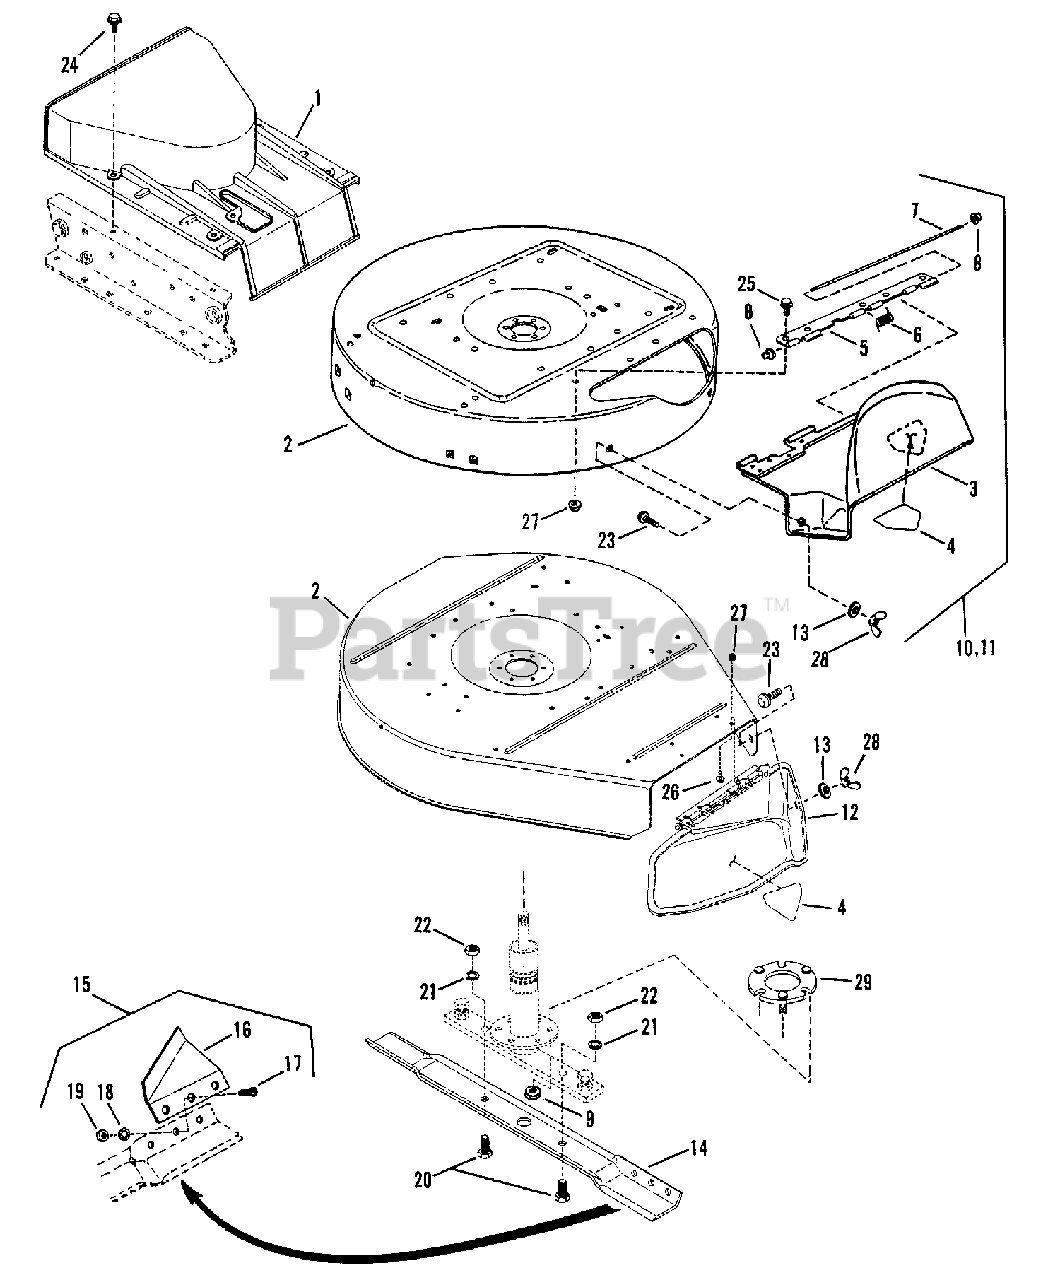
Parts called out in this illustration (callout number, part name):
1	COVER, Spindle
2	25" DECK (Includes decals)
2	26" DECK (Includes decals)
2	28" DECK (Includes decals)
2	30" DECK (Includes decals & deflector)
3	DEFLECTOR, Discharge (25" Deck)
3	DEFLECTOR, Discharge (28" Deck)
4	DECAL, Danger (Cut Finger)
5	HINGE, Deflector
6	SPRING, Hinge
7	PIN, Hinge
8	NUT, 1/4 Push
9	NUT, 3/8-16 Hex Flange Lock
10	ASSEMBLY, Discharge (25" Deck)
11	ASSEMBLY, Discharge (28" Deck)
12	DEFLECTOR, Discharge (26" & 30" Decks)
13	WASHER, 5/16 Flat
14	25" BLADE
14	26" BLADE
14	28" BLADE
14	30" BLADE
15	AIR LIFT KIT, Hi-Vac
16	AIR LIFT, Hi-Vac (3 hole)
17	SCREW, 5/16-24 x 11/16" Machine
18	WASHER, 5/16-24 Internal Tooth Lock
19	NUT, 5/16-24 Hex
20	SCREW, 1/2-20 x 1" Hex Head Cap
21	WASHER, 1/2 Internal Tooth Lock
22	NUT, 1/2-20 Hex Jam
23	BOLT, 5/16-18 x 3/4" Short Neck Carriage
24	SCREW, 1/4-20 x 5/8" Self-Tapping
25	SCREW, 5/16-18 x 5/8" Self-Tapping
26	BOLT, 5/16-18 x 1/2" Hex Flange Lock
27	NUT, 5/16-18 Hex Flange Lock
28	NUT, 5/16-18 Wing
29	RING, Spindle
